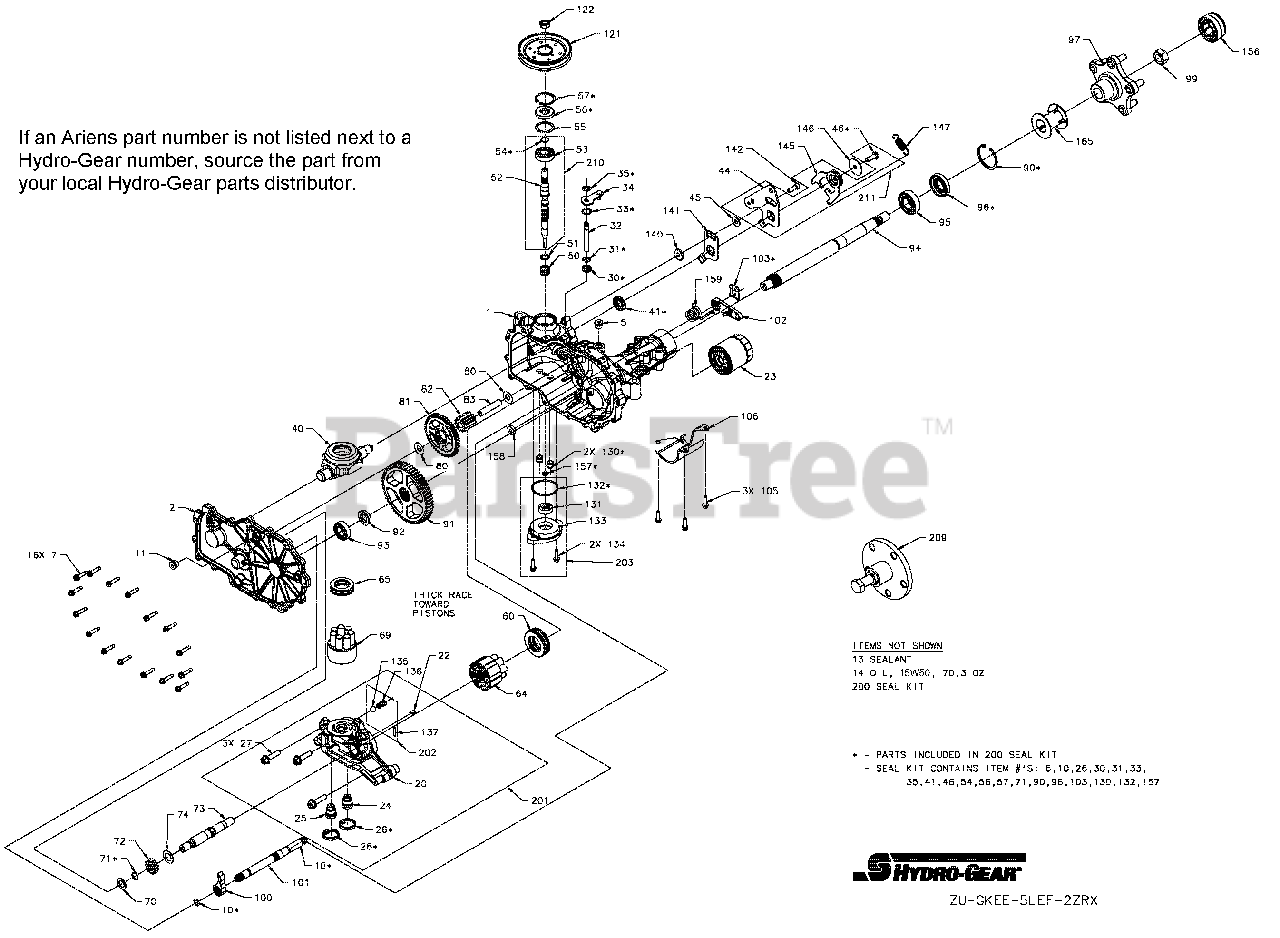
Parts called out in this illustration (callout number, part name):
1	KIT, HOUSING,MAIN,RH,CHRG,CNTL
1	HOUSING, MAIN, RH, CHRG, CNTL
1	BUSHING, .624 x .719 x .562
1	BRG, JRNL .86 x .98 x .79
1	PIN, .25 x .375
2	KIT, COVER, SIDE, RH
2	COVER, SIDE, RH
2	BUSHING, .624 x .719 x .562
2	BRG, JRNL .86 x .98 x .79
5	PLUG 9/16-18 (METAL)
7	HFHCS 1/4-20 x 1.125"
10	O-RING - 111 .103 x 424
11	PLUG 9/16-18 (METAL)
13	SEALANT
14	SYNTHETIC OIL, 15W50
20	CENTER SECTION, RH, CHRG
22	PLATE, BYPASS
23	FILTER, OIL
24	SHOCK VALVE ASSEMBLY 220 BAR
25	SHOCK VALVE ASSEMBLY 220 BAR
25	BEARING, JOURNAL .50 x .59 x .50
26	SEAL, PLUG 1.250 x .250
27	HFHCS 3/8-16 x 1.5 (PATCH)
30	SEAL, LIP .375 x .75 x .25
31	RING, RET .375 EXTRNL
32	ROD, BYPASS
33	RING, RET .750 INTRNL
34	ARM, BYPASS
35	RING, RTNG .375 EXT
40	TRUNNION, SWASHPLATE
41	SEAL, LIP 12 x 32 x 7
44	ARM, CONTROL, RH
45	WASHER .34 x .88 x .06
46	TWHCS 5/16-24 x 1.00 (PATCH)
50	SPRING, BLOCK
51	WASHER-FLAT .59 x .79 x .04
52	SHAFT, INPUT
53	BRG, BALL 17 x 40 x 12
54	RING, RET. WIRE .561
54	RING, RET WIRE .561 ID
55	WASHER 1.23 x 1.56 x .04
56	SEAL, LIP 17 x 40 x 7
57	RING, RETAINING
60	BEARING, THRUST
64	ASS'Y, CYLINDER BLOCK, 16cc
65	BRG, THRUST PLASTIC CAGE
69	ASS'Y, BLOCK 7 PISTON
70	WASHER .63 x 1.0 x .05
71	RING, RETAINING_.625
72	GEAR, 13T, STEEL
73	SHAFT, MOTOR
74	WASHER .72 x 1.16 x .04
80	WASHER .5 x 1.0 x .03
81	GEAR, 46T
82	GEAR, 11T, STEEL
83	JACK SHAFT (PIN)
90	RING, RET 2.06 INT
91	GEAR, 54T
92	SPACER, .750 x 1.320 x .257
93	BEARING, BALL, .75 x 40 x 12
94	SHAFT, AXLE
95	BRG, BALL 25.4 x 52 x 15
96	SEAL, LIP 1.000 x 2.049 x .375
97	KIT, HUB, 5 BOLT
97	HUB, TAPER 3.56, 5 BOLT
97	STUD, 1/2-20 x 1.5 (RIB NECK)
99	NUT, HEX LOCK 3/4-16
100	PAWL, BRAKE
101	SHAFT, BRAKE
102	KIT, HANDLE, ACTUATING
103	CLIP, RETAINING
105	SCREW, HEX FLANGE 1/4-20 x .625
106	GUARD, FILTER, RH
121	PULLEY, 4.5 x 1.625
122	NUT,HEX JAM 1/2-20 W/ PATCH
130	TUBE, CONNECTING
131	GEROTOR ASSEMBLY (1.9 cc/rev)
132	O-RING, -137, 0.103 x 2.050
133	COVER, CHARGE PUMP
134	SCREW, HEX FLANGE 1/4-20 x .625
135	BALL 7/16
136	SPRING, RELIEF
137	PIN, SPRING .125 x .875
140	SPACER .320 x 1.005 x .179
141	ARM, NEUTRAL RIGHT
142	SHCS 5/16-24 x 1 PATCH
145	ASSEMBLY, RTN, CW
146	WASHER, .343 x 1.500 x .062
147	SPRING, EXTNSN RTN-34LBS
157	SEAL, LIP 8 x 12 x 3 VC
158	MAGNET, RING
159	SPRING, TORSION CCW
165	TUBE, AXLE 2.04
200	KIT, SEAL
200	PIN, .25 x .375
201	KIT, CENTER SECTION, RH, CHRG
202	KIT, CHARGE RELIEF
203	KIT, CHARGE PUMP
209	HUB PULLER, 5 BOLT
210	KIT, INPUT SHAFT
211	KIT, RTN, CW
